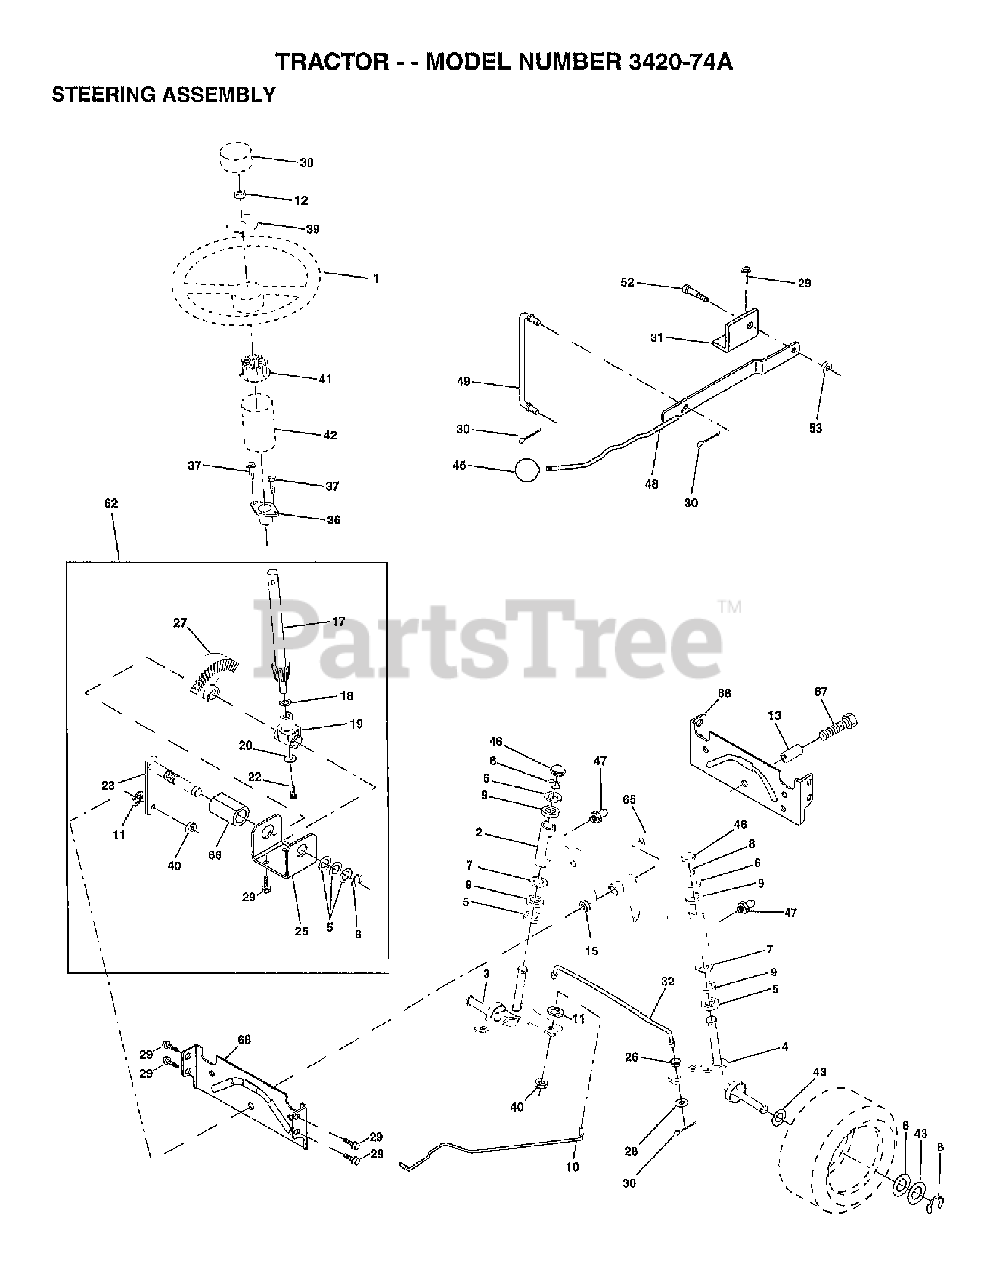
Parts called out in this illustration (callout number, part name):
1	Steering Wheel
2	Half Axle Assembly, Welded
3	SPINDLE.ASM.LH
4	SPINDLE ASM RH
5	WASHER THRUST
8	RING CLIP
9	BEARING.STEERING.COLUMN
10	DRAGLINK-STAMPED
11	WASHER, LOCK 3/8
12	NUT.HEX.1/2-20
13	BEARING AXLE
15	LOCK NUT
17	STEERING SHAFT
18	THRUST WASHER
19	SHAFT,SUPPORT
20	WASHER
23	SHAFT,PITMAN
25	BRACKET STEERING
26	BUSHING STEERING
27	GEAR.SECTOR
28	WASHER
30	COTTER PIN
36	BUSHING STRG 3/4
37	SCREW.TT.#10-32X.5.3/8.FLANGE
38	INSERT STR WHL
40	NUT
46	CAP.SPINDLE.BLACK
47	ZERK.GREASE.TAPERED
62	STEERING KIT
65	SPACER AXLE
66	BEARING ARM
67	BOLT.HEX.FINISHED.5/8
68	AXLE, BRACE
